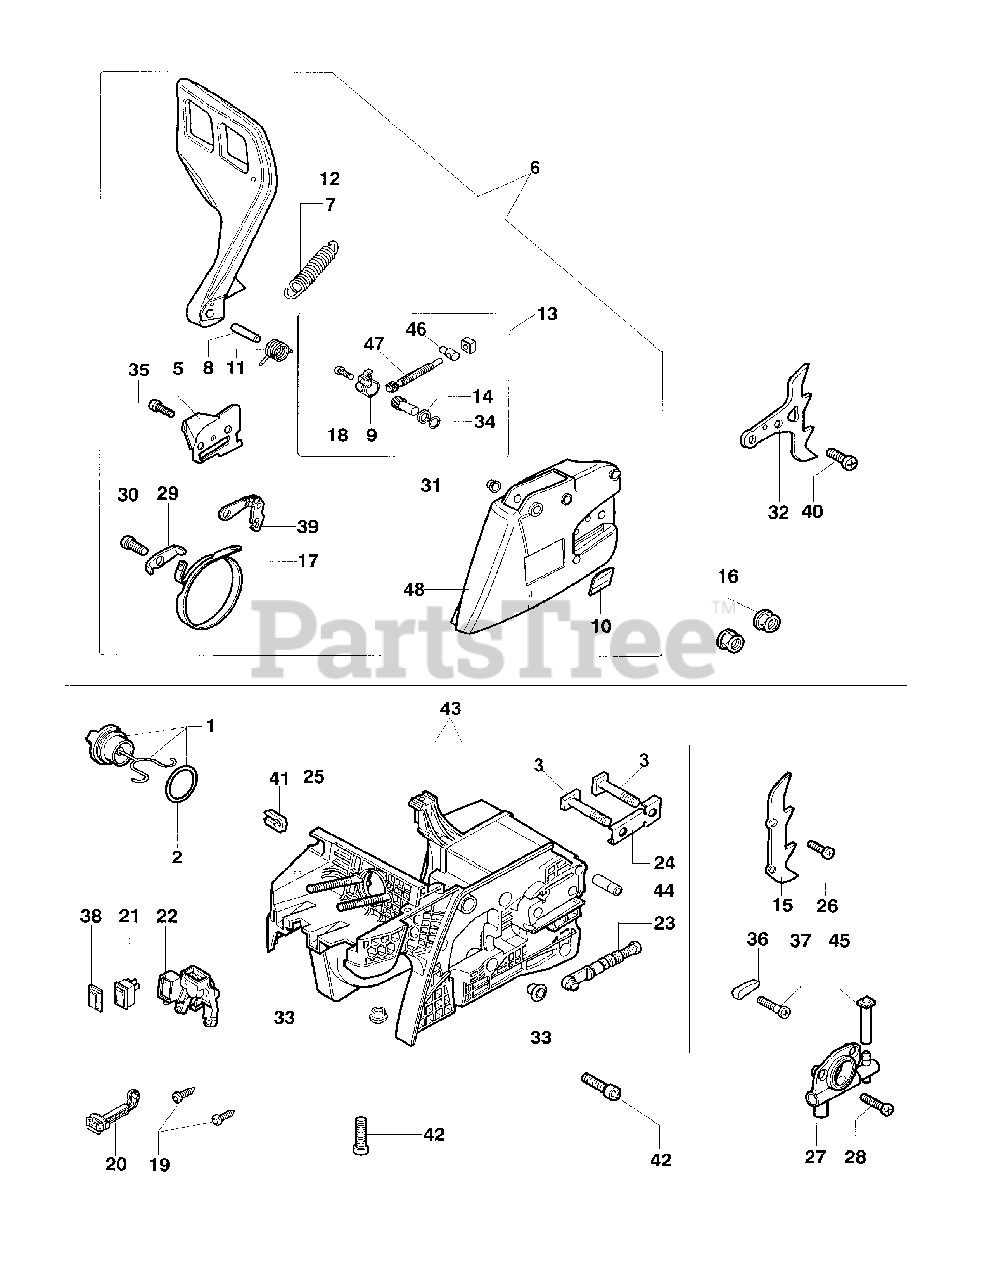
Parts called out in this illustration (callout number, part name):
6	COVER ASSEMBLY
13	CHAIN
20	STARTER LEVER
21	SWITCH
22	FILTER ATTAC.
38	SWITCH GUARD
44	TANKBREATHER
46	TENSIONING NUT
47	ADJUSTING SCREW
48	CHAIN COVER
